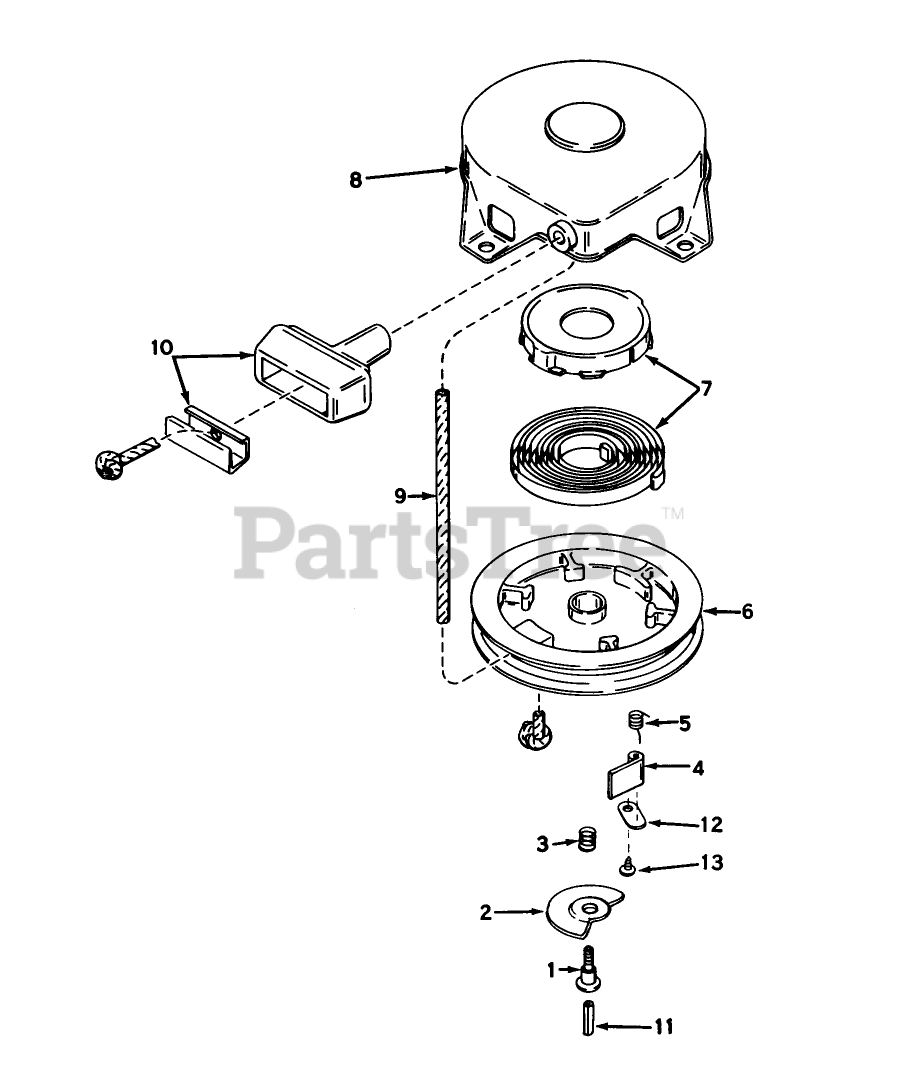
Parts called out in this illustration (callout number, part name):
2	Cam-Dog
3	Spring-Brake
4	Dog-Starter
5	Spring-Dog
7	Spring & Keeper Assy
8	Housing Assembly, Starter (Incl. Ref. #1)
9	Rope-Starter
10	Assy., Starter
11	Centering
12	Retainer-Dog
